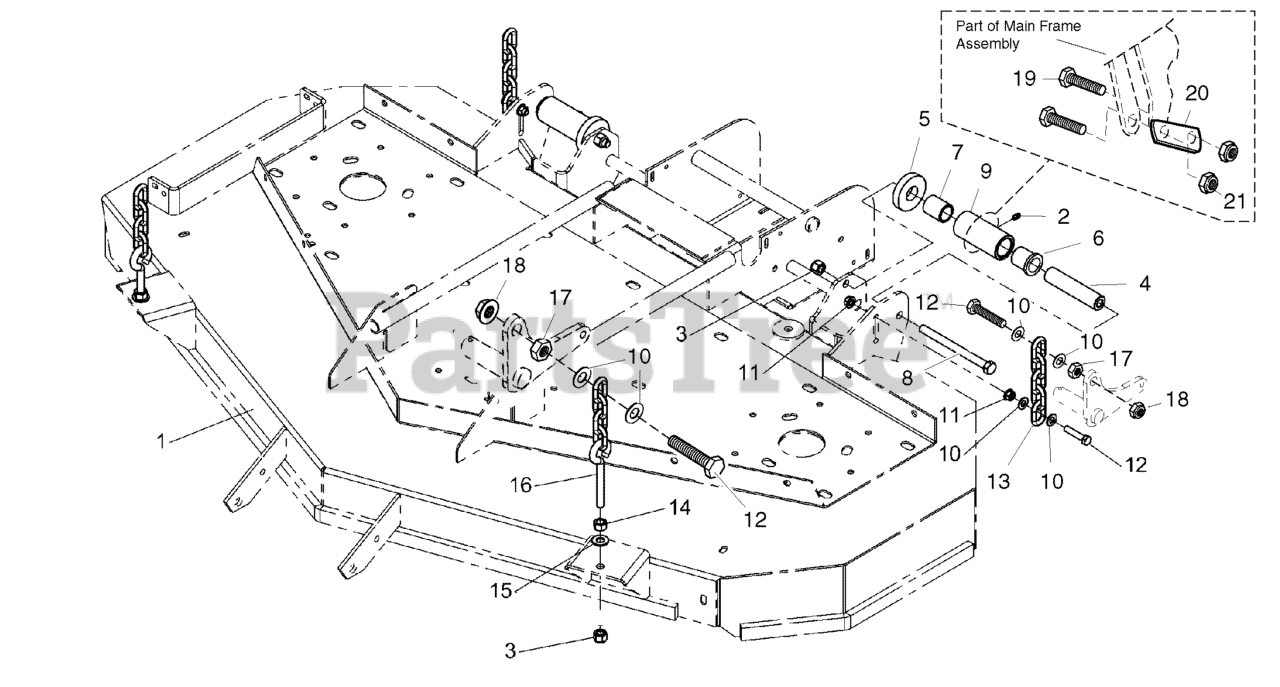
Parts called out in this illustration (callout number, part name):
1	MOWER DECK
2	GREASE FITTING
3	NUT, Hex Flange, Nylock, 1/2-13
4	SPACER, .52 X 1.00 X 4.56
5	WASHER, FRICTION
6	BUSHING, FLANGE
7	BUSHING, 1.00 X 1.25 X 1.50 PL
8	BOLT, 1/2-13 X 6" GD5 YZ
9	ROLLER, MULE DRIVE - RED
10	WASHER, 3/8 SAE
11	NUT, 3/8-16 HEX SERRATED FLANGE
12	BOLT, 3/8-16 X 1-3/4" GD5 CZ
13	CHAIN, 5/16" GD30, 5 LINKS
14	NUT, 1/2-13 HEX
15	WASHER, 1/2 SAE
16	HANGER, FRONT DECK - 4 LINK, 5.5" EB
16	HANGER, FRONT DECK - 5 LINK, 5.5" EB
17	NUT, 3/8-16 HEX JAM
18	NUT, 3/8-16 Nylock Flange
19	BOLT, 1/2-20 X 1-3/4" GD8 CZ
20	BAR, PUSHER BAR SUPPORT
21	NUT, Hex, Nylon Lock, 1/2-20
